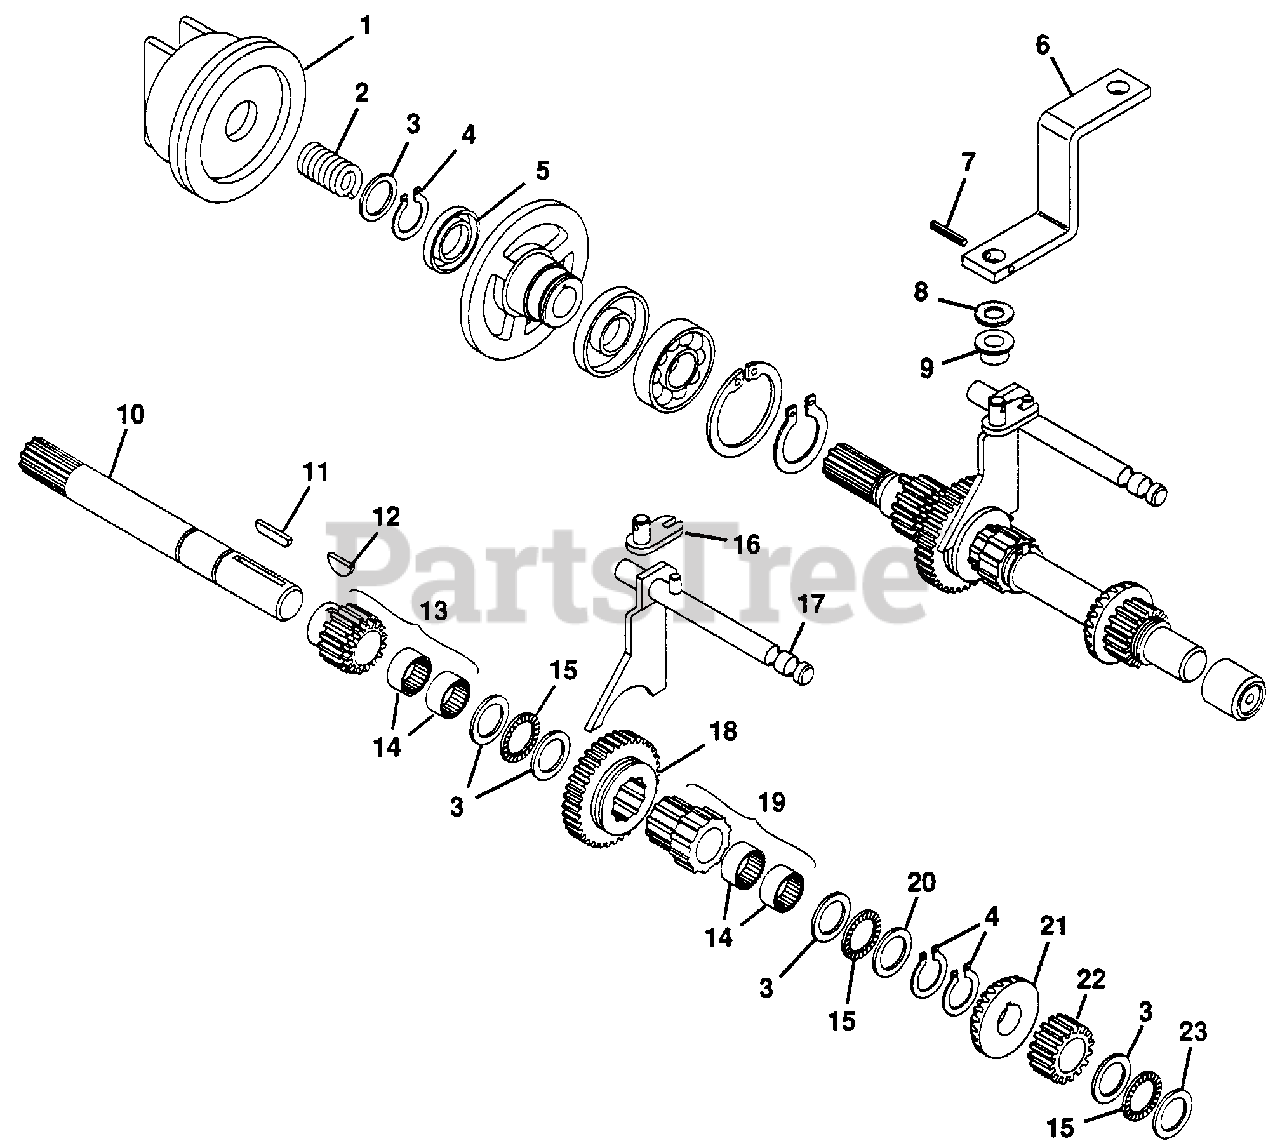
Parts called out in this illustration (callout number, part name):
1	Number 11 - Fwd-Rev Clutch Asm.
2	Spring, Comp. 1.0x.80x36 lb/in
3	Race, Brg Thrust .752x1.240x.030
4	Ring, Retaining .750 Shaft
5	Seal, Oil
6	Arm, Shifter
7	Pin, Spring .188x1.00
8	Washer, Felt
9	Bushing, 2-Speed
10	Shaft, Fwd Clutch
11	Key, Woodruff .188x1.25 Hrd #19
12	Key, Woodruff .188x.625 Hrd #61
13	Gear and Bearing Assembly
14	Bearing, Needle .75x1x.50
15	Bearing, Thrust .752x1.240x.078
16	Weldment, Shifter
17	Weldment, Shift Rail
18	Gear, Spur 2 Speed 10DP 36T
18	Gear, Spur 2 Speed 10DP 26T
19	Gear and Bearing Assembly
20	Race, .060 Bearing Thrust
21	Gear, Bevel
22	Gear, 10 DP 16 Teeth x .750 Std.
23	Race, Thrust .752x1.240x.095
